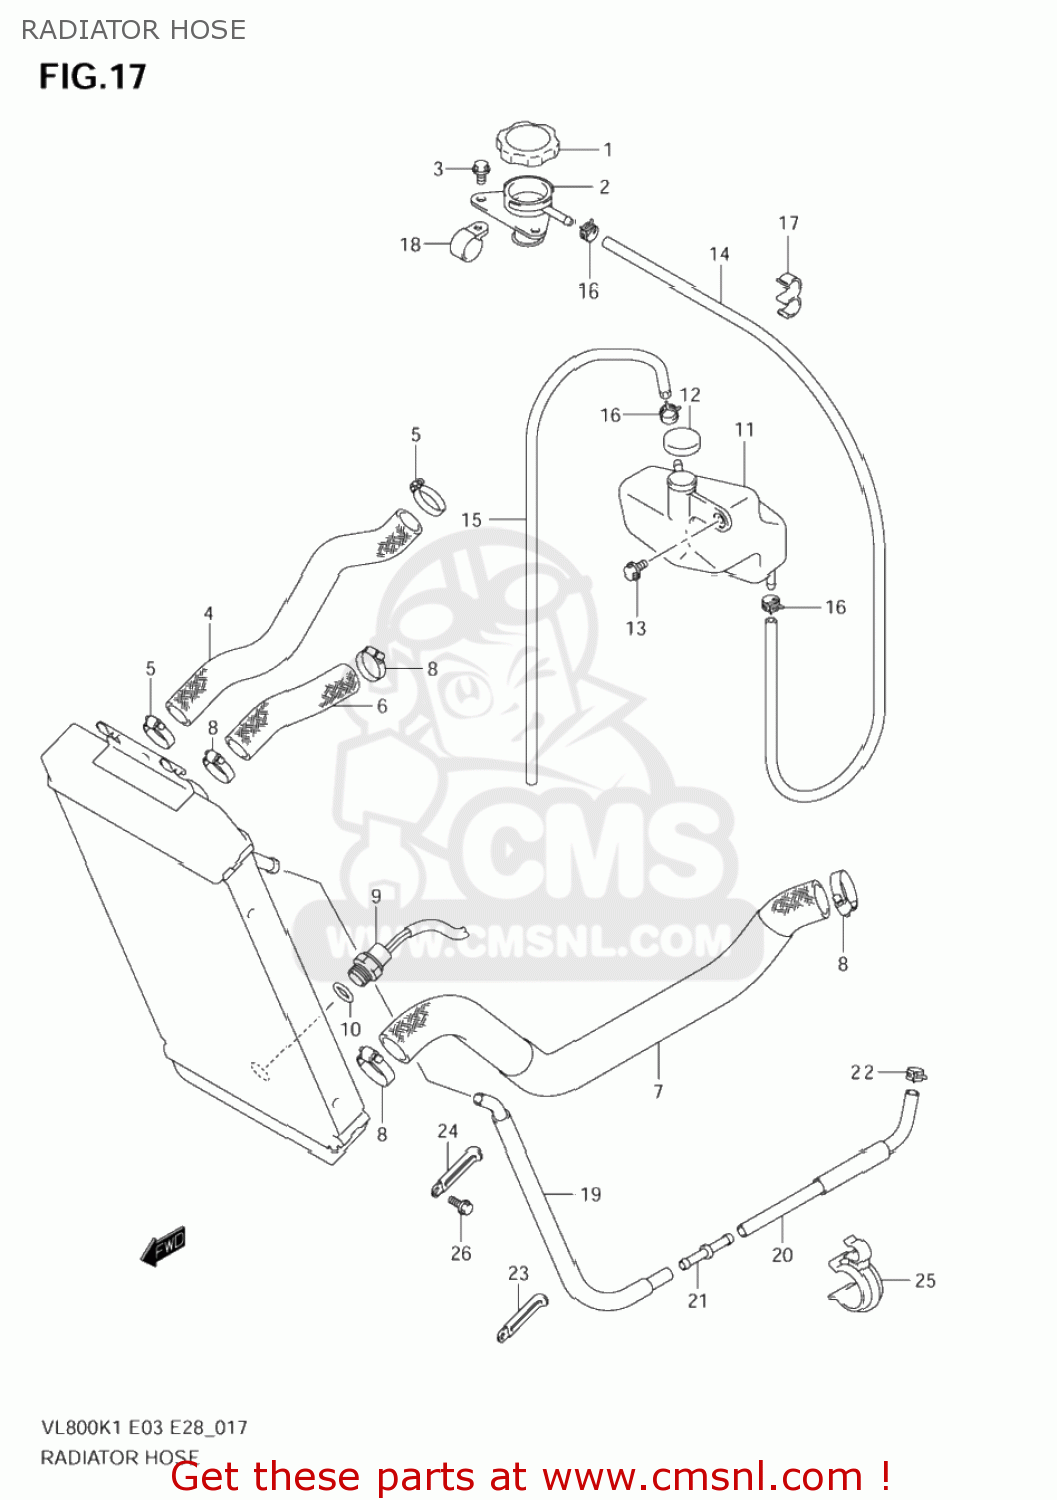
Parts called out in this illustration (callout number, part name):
1	CAP,RADIATOR
2	CONDUCTION,RADIATOR
3	BOLT
4	HOSE,CONDUCTION
5	CLAMP
6	HOSE,RADIATOR INLET
7	HOSE RDTR OUTL
8	CLAMP
9	SWITCH,RADIATOR FAN
10	O-RING
11	TANK,RESERVOIR
12	CAP,RESERVOIR TANK
13	BOLT
14	HOSE,RESERVOIR
15	HOSE,RESERVOIR TANK INLET
16	CLIP
17	CLIP
18	CLAMP
19	HOSE,WATER BYPASS
20	HOSE,WATER BYPASS
21	JOINT
22	CLAMP
23	CLAMP(L:80)
24	CLAMP(L:62)
25	CLAMP
26	BOLT
